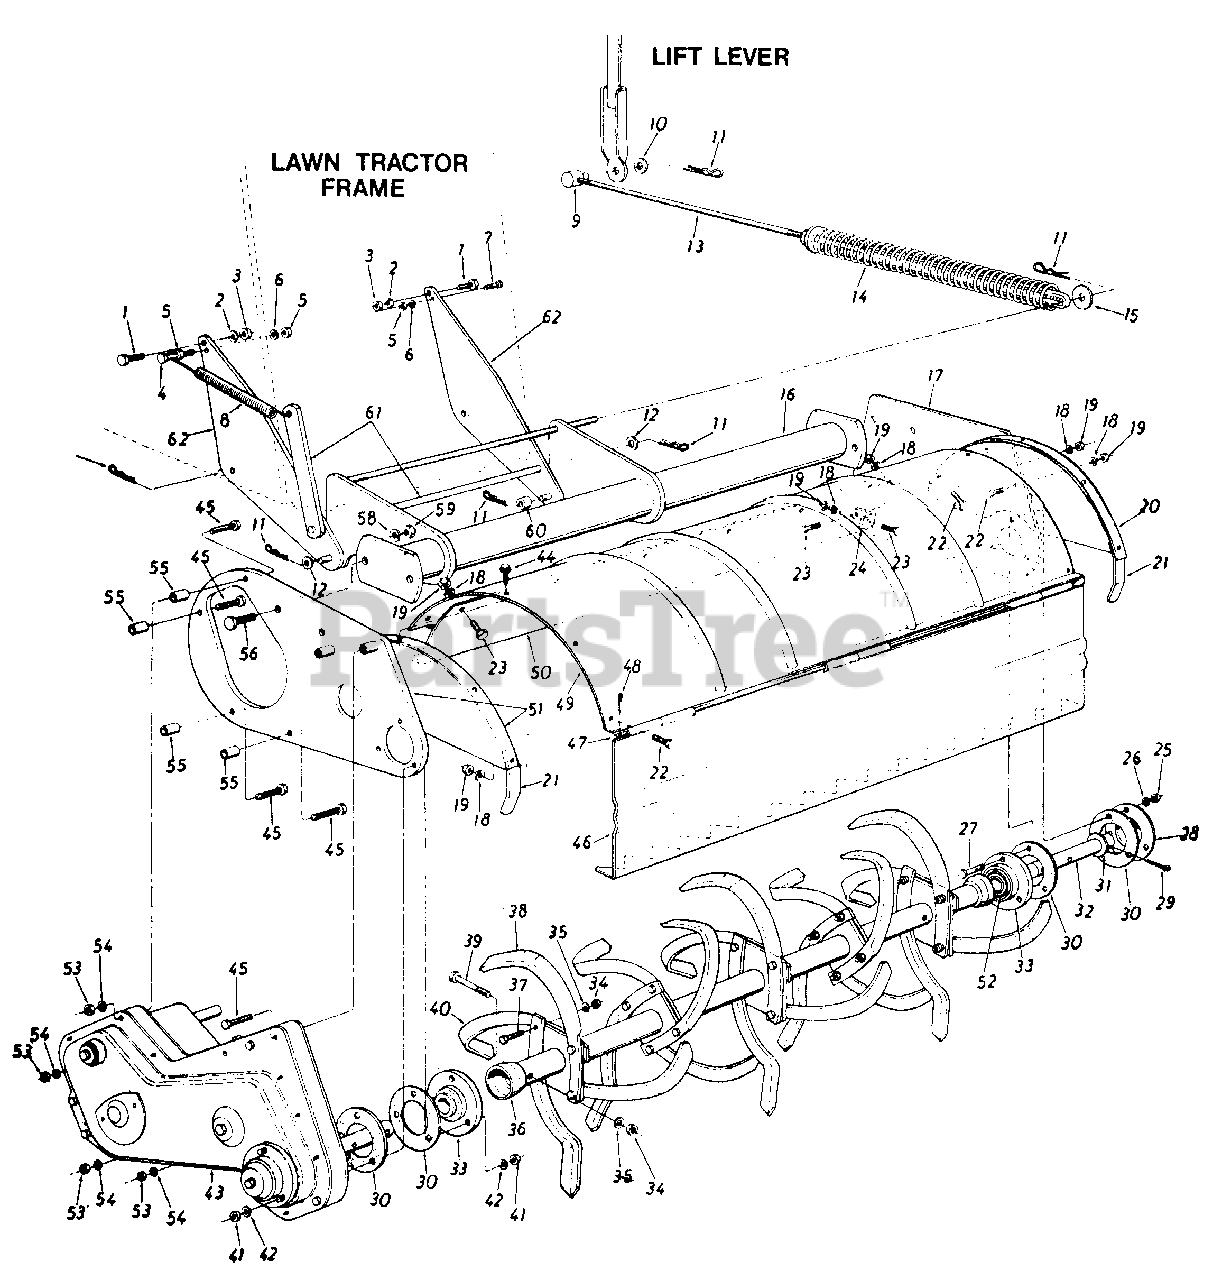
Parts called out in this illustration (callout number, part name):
1	Hex Bolt 3/8-24 x .88" Lg.
2	L.-Wash. 3/8" I.D. Heavy Duty
3	Hex Nut 3/8-24 Thd.
4	Hex Bolt 5/16-24 x 1.50" Lg.
5	Hex Nut 5/16-24 Thd.
6	L.-Wash. 5/16" I.D.
7	Hex Bolt 5/16-24 x 1.00" Lg
8	Lxt 8prlng .56" O.D. x 7.75" Lg.
9	Adjustment Ferrule 1/2-13 Thd.
10	Fl.-Wash. .640" I.D. x 1.24" O.D. x .060
11	Intern. Cotter Pin 1/2" Dia.
12	Fl.-Wash. .510" I.D. x 1.0" O.D. x .060
13	Lift Rod Ass'y. 39.0" Lg.
14	Compression Spring 1.50" O.D. x 15.0" Lg.
15	Fl.-Wash. .51" I.D. x 1.50" O.D. x .075
16	Pivot Bracket Assembly
19	Hex Nut 5/16-24 Thd.
23	Hex Bolt 5/16-24 x .62" Lg.
24	Chute Pivot Bracket
25	Hex Cent. L-Nut 5/16-18 Thd.
26	L.-Wash. 5/16" I.D.
27	Hex Bolt 5/16-18 x 1.0" Lg. (Grade 5)
30	Gasket for Brg. Housing
31	Fl.-Wash. 1.25" I.D. x 2.00" 0. D. x .06
32	Tine Shaft R.D. 1.25" Dia. x 6.25" Lg.
33	Bearing Housing w/Bearing
34	Hex Nut 3/8-24 Thd.
35	L.-Wash. 3/8" I.D. Heavy Duty
41	Hex Cent. L.-Nut 5/16-18 Thd .
42	L.-Wash. 5/16" I.D.
43	Chain Case Ass'y. Comp.
44	Hex Wash. TT Tap. Scr. 5/16-18 x .62" Lg.
45	Hex Bolt 1/4-20 x 2.75" Lg.
48	Cotter Pin 1/8" Dia. x 1.00 Lg.
53	Hex Nut 1/4-20 Thd.
54	L.-Wash. 1/4" I.D.
55	Spacer .28" I.D. x .62" O.D. x .90 " Lg.
56	Hex Bolt 1/2-13 x 1.00" Lg.
58	L.-Wash. 1/2" I.D.
59	Hex Nut 1/2-13 Thd.
60	Spacer .50" I.D. x 1.00" O.D. x .50" Lg.
61	Idler Bracket Support Arm Ass'y
